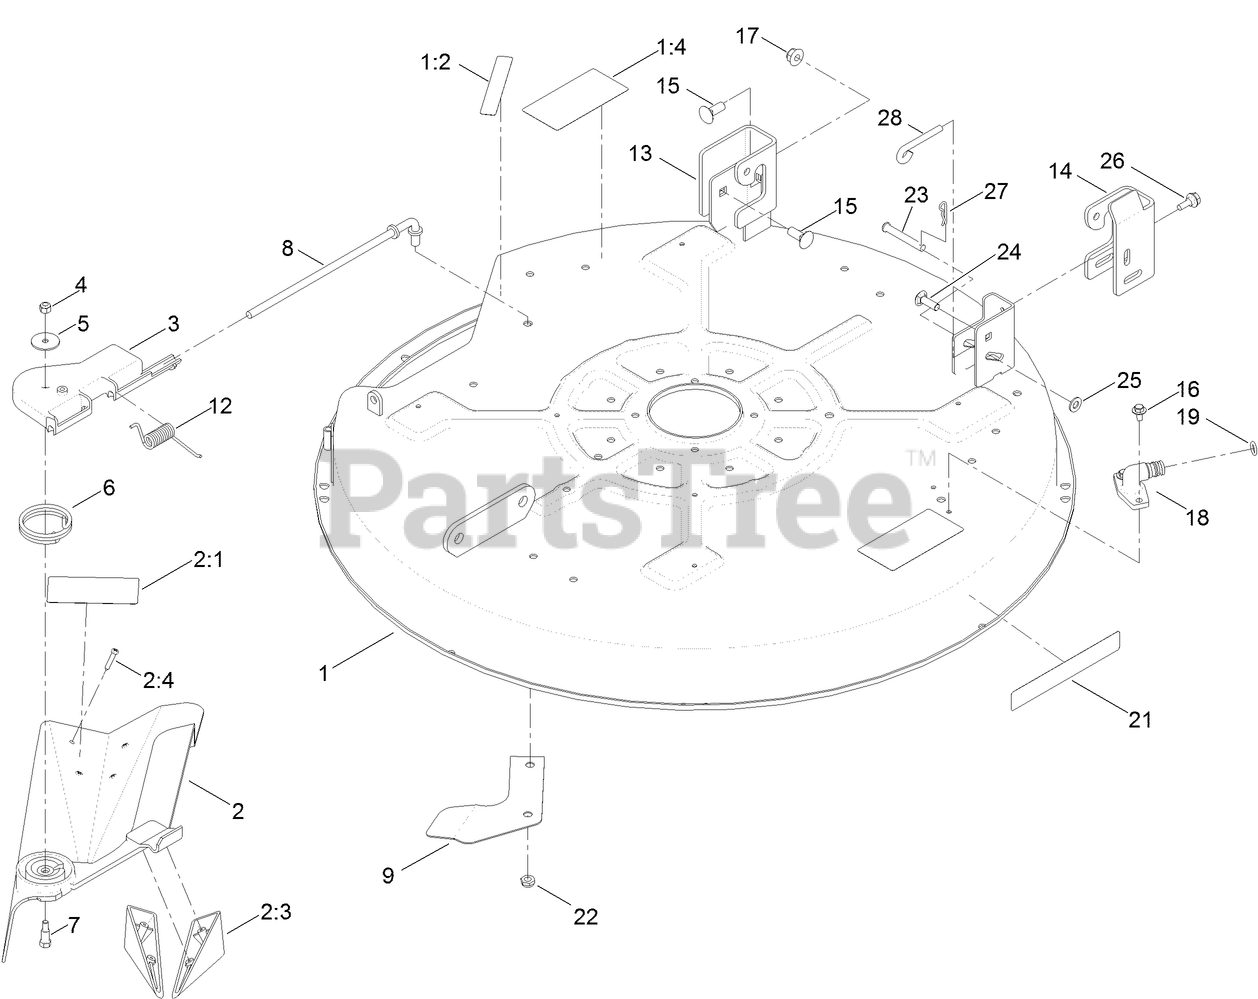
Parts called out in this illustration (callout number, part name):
1	32 INCH DECK AND DECAL ASM
1:2	DECAL-DANGER
1:4	DECAL-DANGER, DECK
2	32 INCH DEFLECTOR ASM
2:1	DECAL-DANGER
2:3	KICKER
2:4	SCREW-PPH
3	PIVOT-HINGE, DEFLECTOR
4	NUT-LOCK, NI
5	WASHER-FLAT
6	SPRING-TORSION
7	BOLT-SHOULDER
8	ROD-PIVOT
9	RAMP-DEFLECTOR
12	SPRING-TORSION
13	BRACKET-HANGER, RH
14	BRACKET-HANGER, LH
15	BOLT-CARR
16	SCREW-HHFTF
17	NUT-HF, NI
19	O-RING
21	DECAL-RECYCLER
23	PIN-CLEVIS
24	SCREW-CARR
25	WASHER-PLAIN
26	SCREW-SHOULDER,HWH
27	PIN-COTTER
28	ROD-LEVEL, DECK
